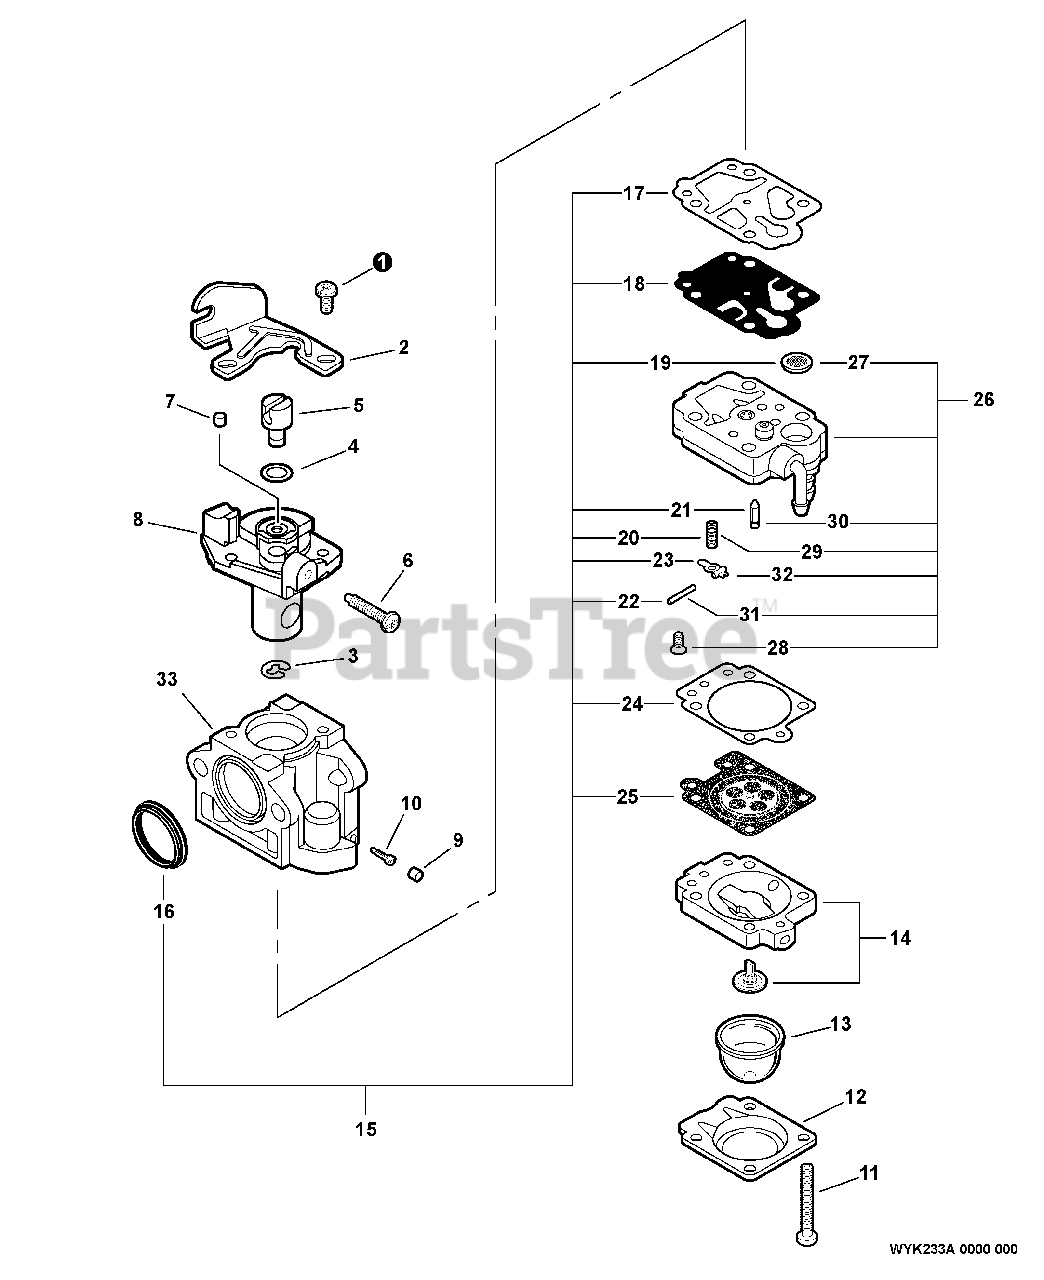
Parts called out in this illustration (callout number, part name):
2	BRACKET, THROTTLE CABLE
8	THROTTLE VALVE ASSY
10	NEEDLE, HIGH SPEED
12	RETAINER, PURGE BULB
13	BULB, PURGE
14	BODY ASSY, PURGE
15	REPAIR KIT, CARBURETOR
16	SEAL
17	GASKET, PUMP
18	DIAPHRAGM, PUMP
19	STRAINER
20	SPRING, METERING LEVER
21	VALVE, INLET NEEDLE
22	PIN, METERING LEVER
23	LEVER, METERING
24	GASKET, DIAPHRAGM
25	DIAPHRAGM, METERING
26	BODY ASSY, PUMP
27	STRAINER
29	SPRING, METERING LEVER
30	VALVE, INLET NEEDLE
31	PIN, METERING LEVER
32	LEVER, METERING
33	BODY, CARBURETOR
